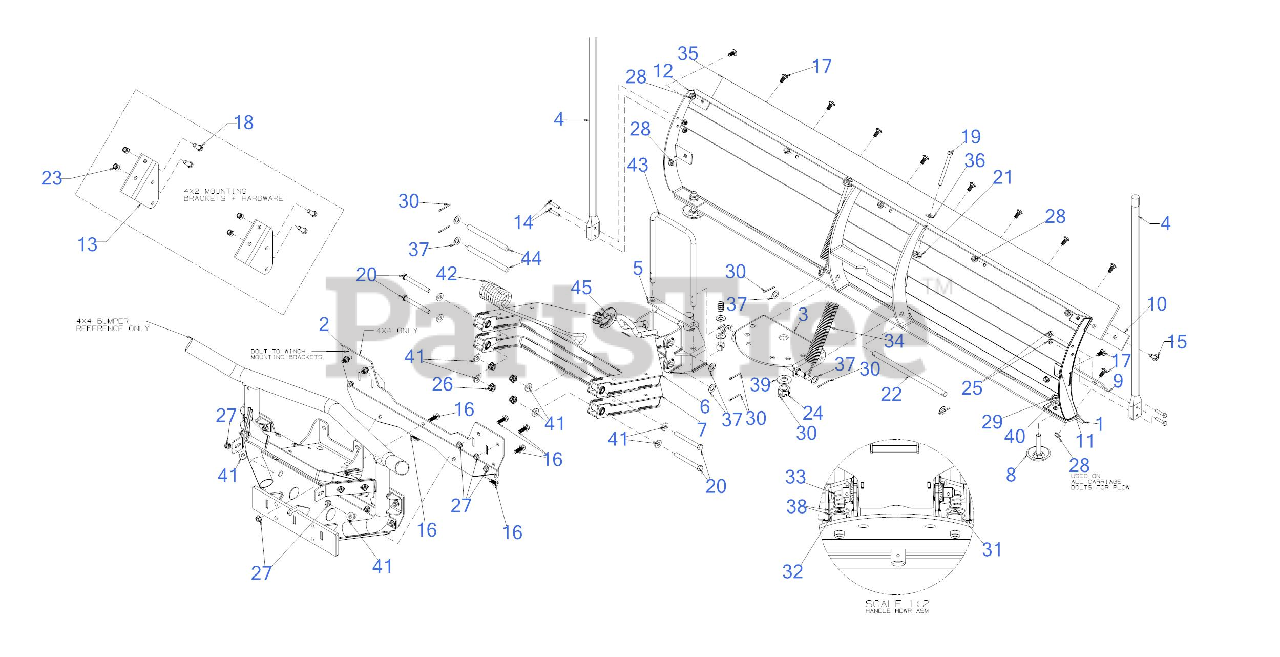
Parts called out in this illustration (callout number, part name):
4	SNOW BLADE GUIDE
14	HEX SCREW 1/4-20 x 1.25
15	CARRIAGE BOLT 5/16-18 x 1.00
16	SCREW 5/16-18 x 1 GR5
17	CARRIAGE BOLT 5/16-18 x .75
18	SCREW 3/8-16 x 1 GR5
19	SCREW 5/16-18 x 3.50 GR5
20	SCREW 3/8-16 x 3.50 GR5
21	INSERT SPRING
22	ROD .50 x 10.428"
23	HEX NUT INS L-3/8-16
24	HEX NUT CASTLE 3/4-16
25	FLANGE LOCK NUT
27	FLANGE NUT 5/16-18
28	HEX FLANGE NUT
29	HEX NUT
30	COTTER PIN
32	CLIP SPACER
33	COMPRESSION SPRING
34	EXTENSION SPRING
35	58" BLADE TRIM
36	FLAT WASHER
37	FLAT WASHER
38	FLAT WASHER .510 x 1.00 x .060
39	FLAT WASHER
40	LOCK WASHER 1/2
41	FLAT WASHER
42	WINCH CABLE FOR SNOW PLOW 5/16"
43	HANDLE LOCK ROD
44	PLOW PIN ROD
45	CLEVIS PIN HOOK
